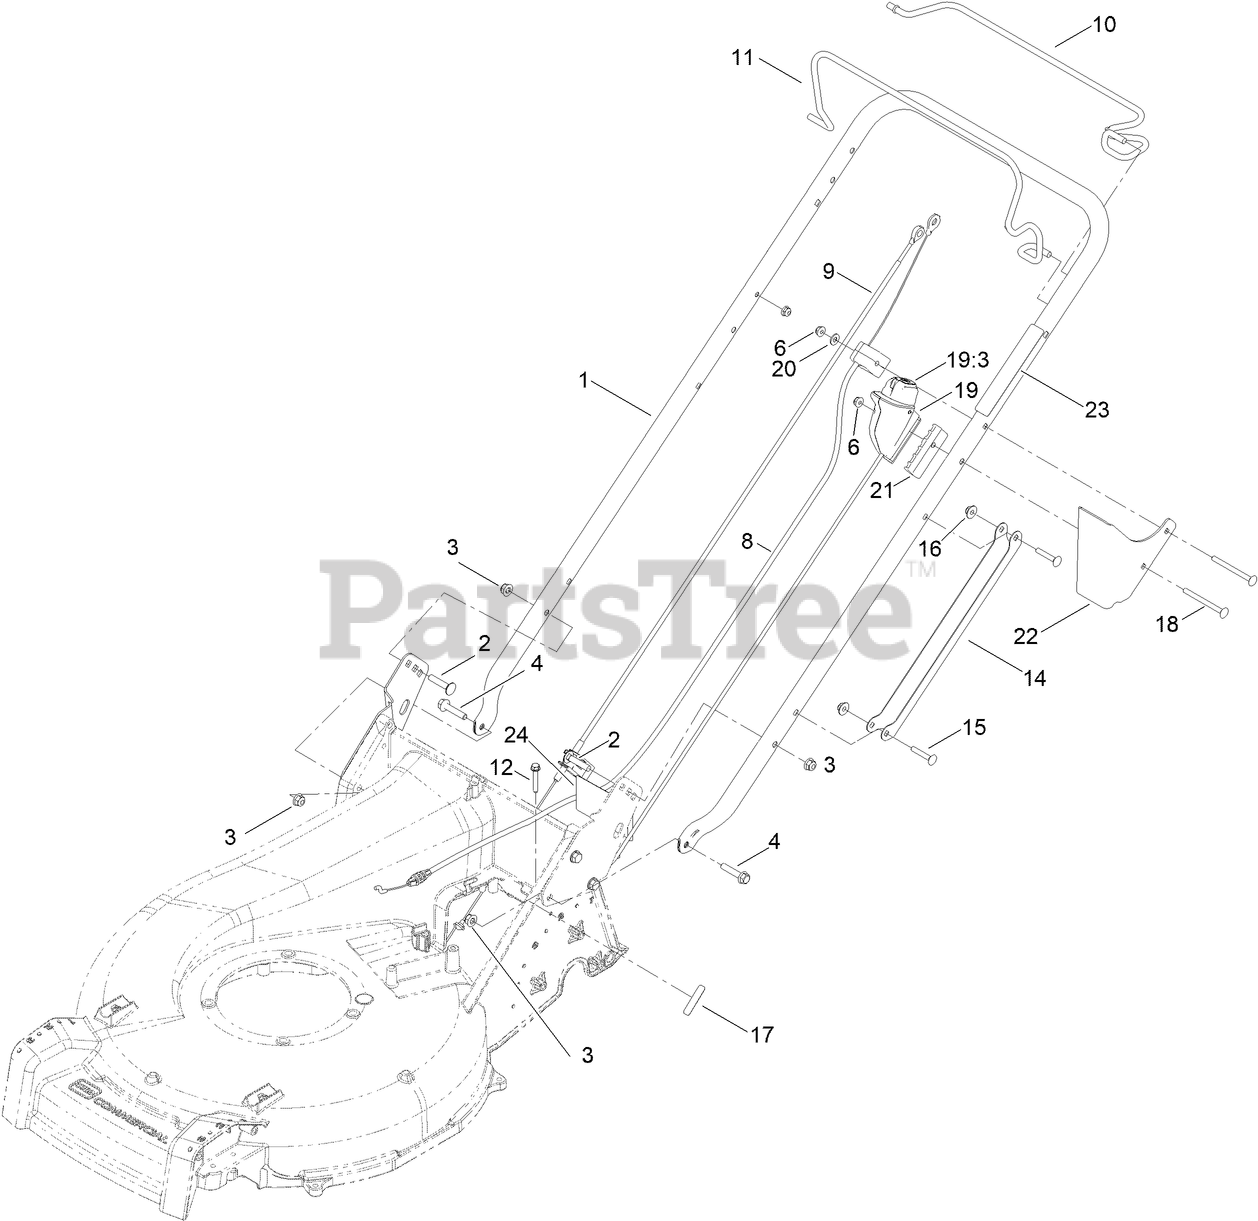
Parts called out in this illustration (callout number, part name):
2	BOLT-CARR
3	NUT-HF, NI
4	SCREW-HHF
6	NUT-HF
8	CABLE-BRAKE, 60V
9	CABLE-TRACTION, 60V
10	BAIL-TRACTION
11	BAIL-BRAKE
12	SCREW-HWH
14	GUARD-CABLE, HANDLE
15	SCREW-CARR
16	NUT-HF
18	SCREW-CARR,SPCL
19	STARTER SWITCH ASM
19:3	STARTER BUTTON SERVICE ASM
20	WASHER-FLAT
21	SPACER-HOUSING, SWITCH
22	GUARD-HOUSING, SWITCH
23	DECAL-CONTROLS (60V START)
